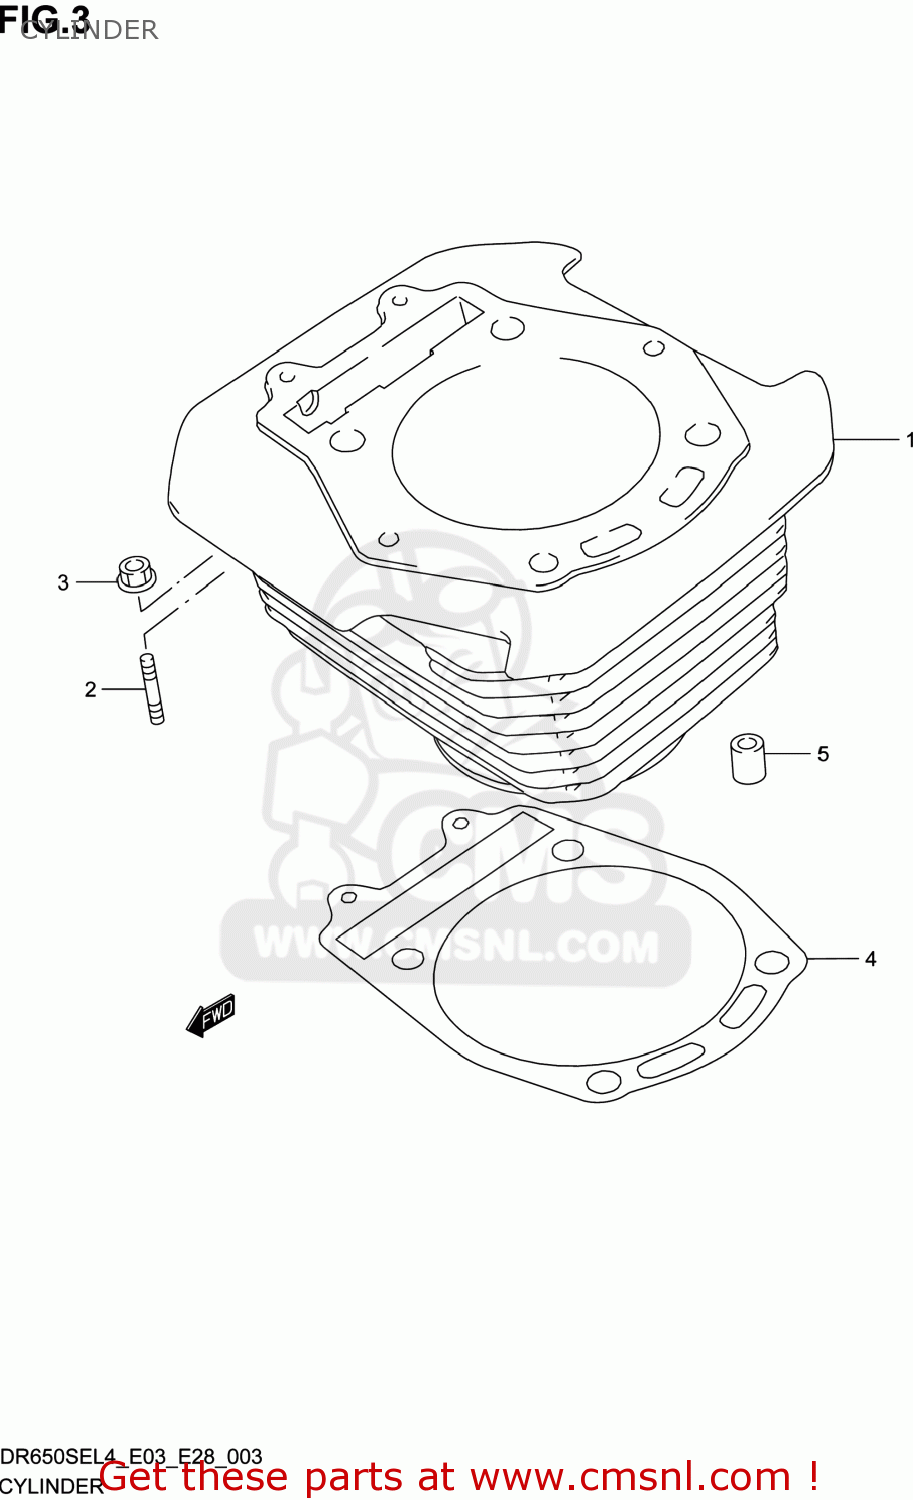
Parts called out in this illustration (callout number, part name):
1	CYLINDER
2	BOLT,STUD
3	NUT
4	GASKET,CYLINDER (NAS)
5	PIN
